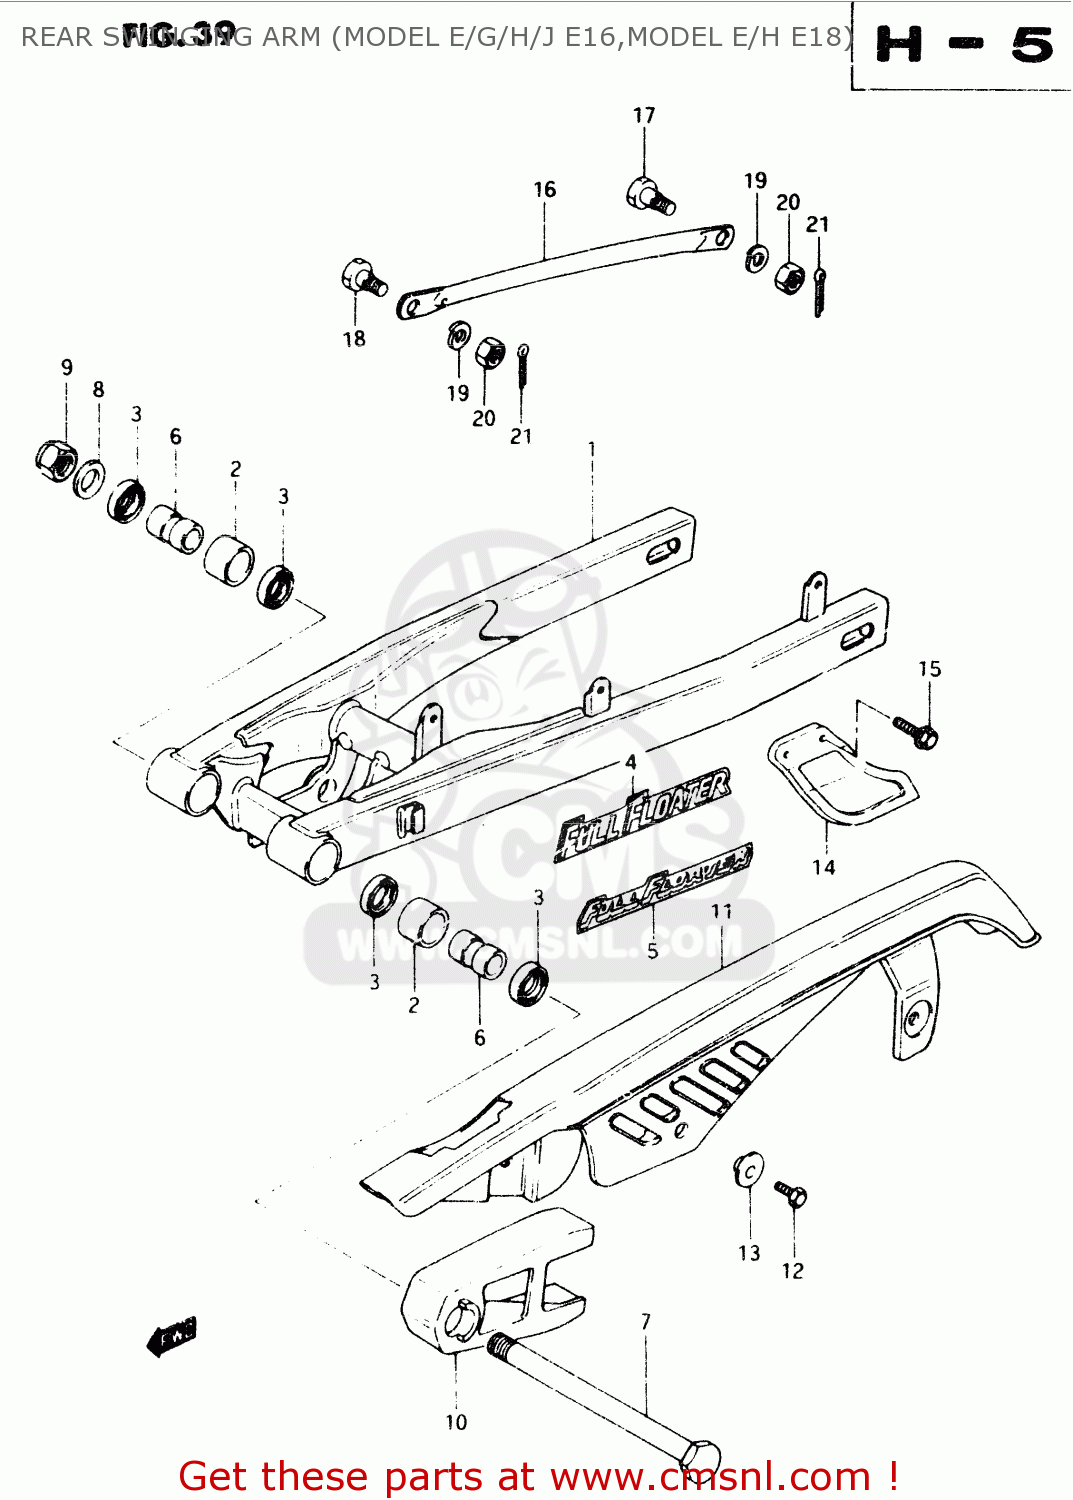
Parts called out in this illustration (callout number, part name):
1	SWINGING ARM ASSY, REAR (GOLD)
2	BUSHING,RR SWGARM PIVOT
3	OIL SEAL
4	EMBLEM
5	EMBLEM,SWING ARM
6	SPACER,RR SWINGING ARM PIVOT
7	SHAFT,RR
8	WASHER
9	NUT 14MM
10	BUFFER,CHAIN TOUCH DEFENCE
11	CASE,CHAIN
12	BOLT
13	WASHER
14	GUIDE,CHAIN
15	BOLT
16	TORQUE LINK,RR
17	BOLT(8X26.5)
18	BOLT(8X22)
19	LOCK WASHER
20	NUT
21	PIN 20X20
